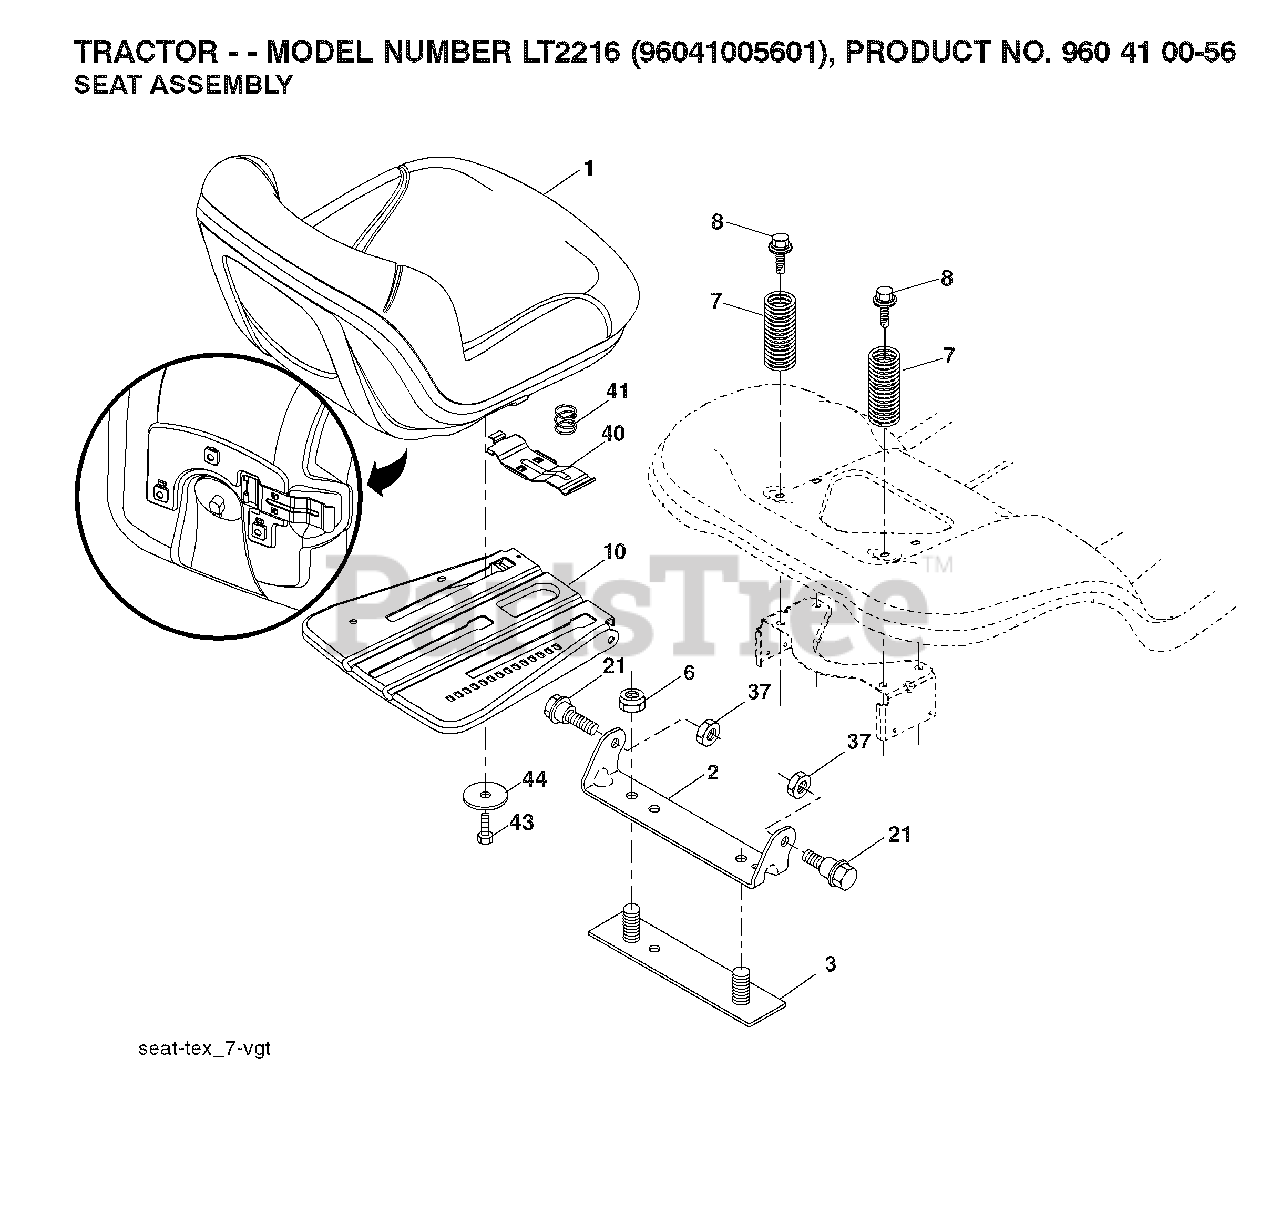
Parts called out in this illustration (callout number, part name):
1	SEAT.TG130.BLACK.NO/LOGO.
2	BRKT.PIVOT.FENDER
6	NUT
7	SPRING COMPRESSION
8	BOLT, 5/16-18 X 1 3/4
10	PAN.ASM.SEAT.3PT
21	BOLT.SHOULDER.5/16-18
37	NUT.71038.31-18.HEX.NYLOCK
40	HANDLE.SLIDE.SEAT.TEX.BLACK
41	SPRING.LATCH.SEAT.TEX
44	WASHER 13/32 X 2-3/8 X 12GA
